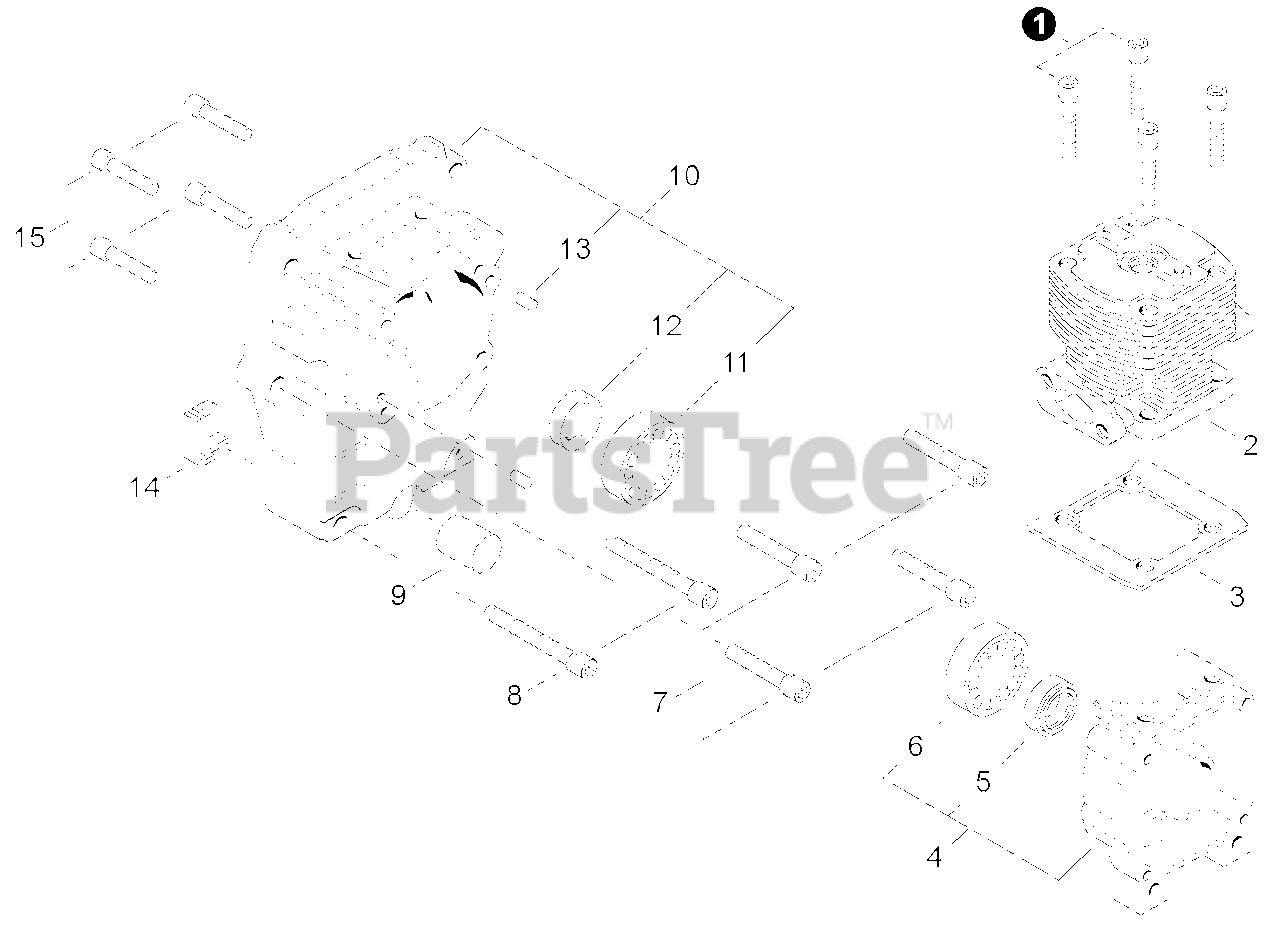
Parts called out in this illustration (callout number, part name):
1	SCREW - 5
2	CYLINDER
3	GASKET, CYLINDER
4	CRANKCASE ASSY - REAR
5	SEAL, OIL - 15
6	BEARING, BALL - 6202C3
7	BOLT - 6X30
8	BOLT - 6X45
9	CUSHION
10	CRANKCASE ASSY - FRONT
11	BEARING, BALL - 6202C3
12	SEAL, OIL - 15
13	PIN - LOCATING
14	GROMMET
15	SCREW - 5X30
